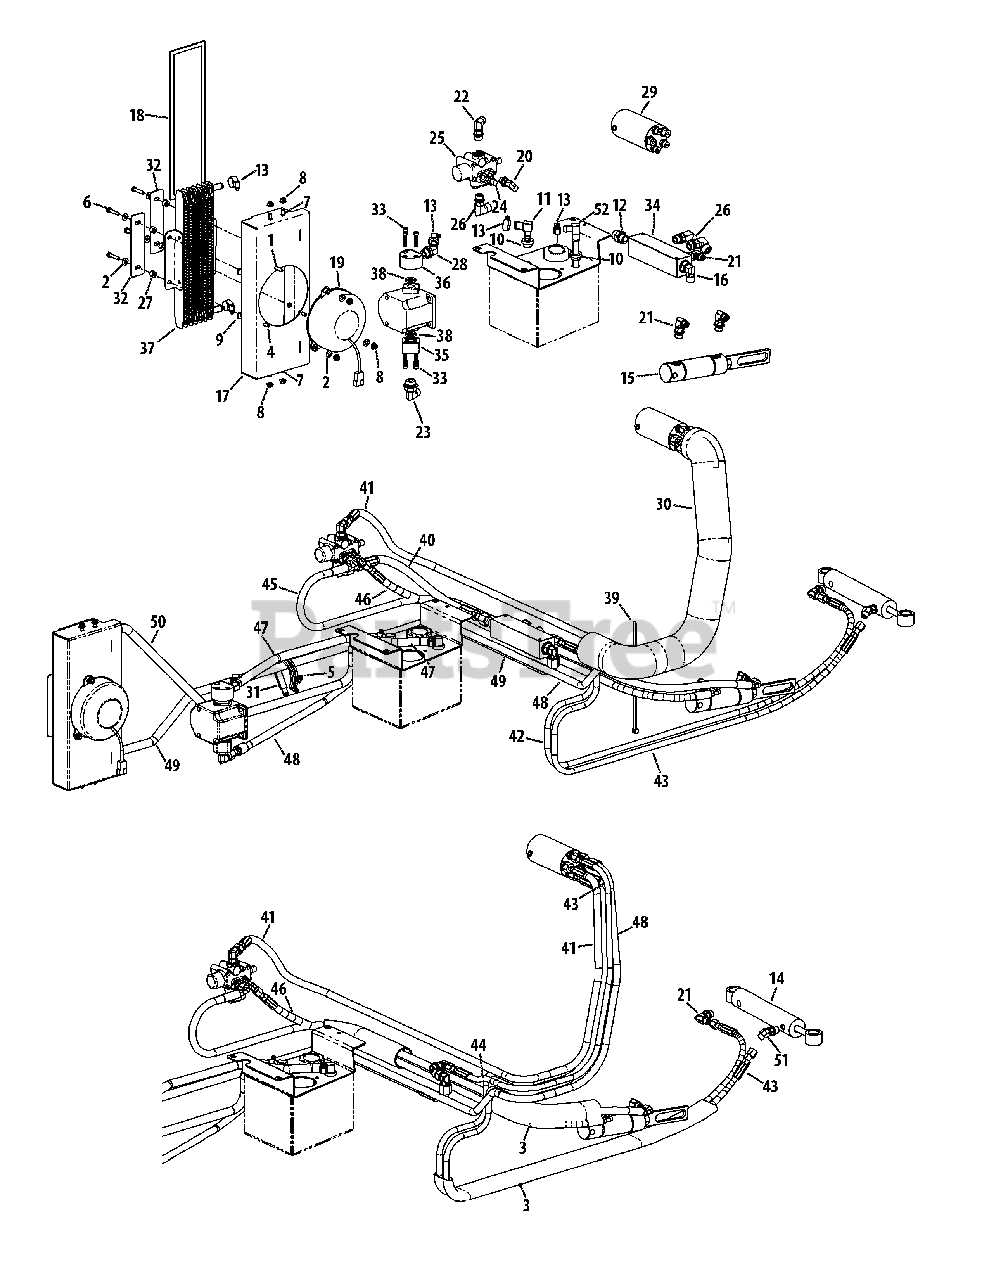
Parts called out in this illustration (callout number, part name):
1	Hex Screw, 1/4-20 x 1.00
2	Washer, .281 x .625 x .063
4	Hex Screw, 1/4-20 x .620
5	Hex Flange Screw, 1/4-20 x .500
6	Hex Screw, 1/4-20 x 1.25
7	Carriage Bolt, 1/4-20 x .620
8	Flange Top Lock Nut, 1/4-20
9	Nut, 1/4-20
10	Grommet, .54 x .78
11	Elbow Fitting, 5/8 x 1/2
12	Hydro Adapter
13	Hose Clamp
14	Steering Cylinder
15	Hydro Cylinder, 1.50 x 2.75
16	Hydro Adapter
17	Radiator Housing Assembly
18	Heat Exchanger Screen
20	Elbow Fitting, 40RB-40RS
21	Elbow Fitting, 40RS-60RB
22	Elbow Fitting, 60RB-60RS
23	Elbow Fitting, 60RS-80RB
24	Elbow Fitting, 40RB-40RS
25	Dual Action Lift Hydro Valve
26	Elbow Fitting, 80RS-60RB
27	Spacer, .256 x .500 x .330
28	45° Fitting, 3/4 x 1/2
29	Hydro Steering Valve
30	Anti-Abrasion Sleeve
31	Loop Clamp, 2.00 x 3.50
32	Hydro Cooler Screen Retainer Brkt.
33	Socket Head Screw, 6-1.0
34	Hydro Manifold, 08 x 06
35	Pump Adapter Fitting Mount
36	Suction Hydro Fitting, 3/4-16
37	Oil Radiator
38	O-Ring, .734 x .139
39	Cable Tie
40	Lift Valve to Manifold Hose Assy.
41	Lift Valve to Steering Valve Assy.
42	Steering Ext. to Steering Valve Hose Assy.
43	Steering Ret. to Steering Valve Hose Assy.
44	Manifold to Steering Valve Hose Assy.
45	Cylinder Ret. to Lift Valve Hose Assy.
46	Cylinder Ext. to Lift Valve Hose Assy.
47	Tank to Pump Hose Assembly
48	Pump to Steering Valve Hose Assy.
49	Manifold to Exchanger Hose Assy.
50	Exchanger to Tank Hose Assy.
51	45° Elbow Fitting
52	Elbow, 1/2 x 5/8 Barb w/ Straw
